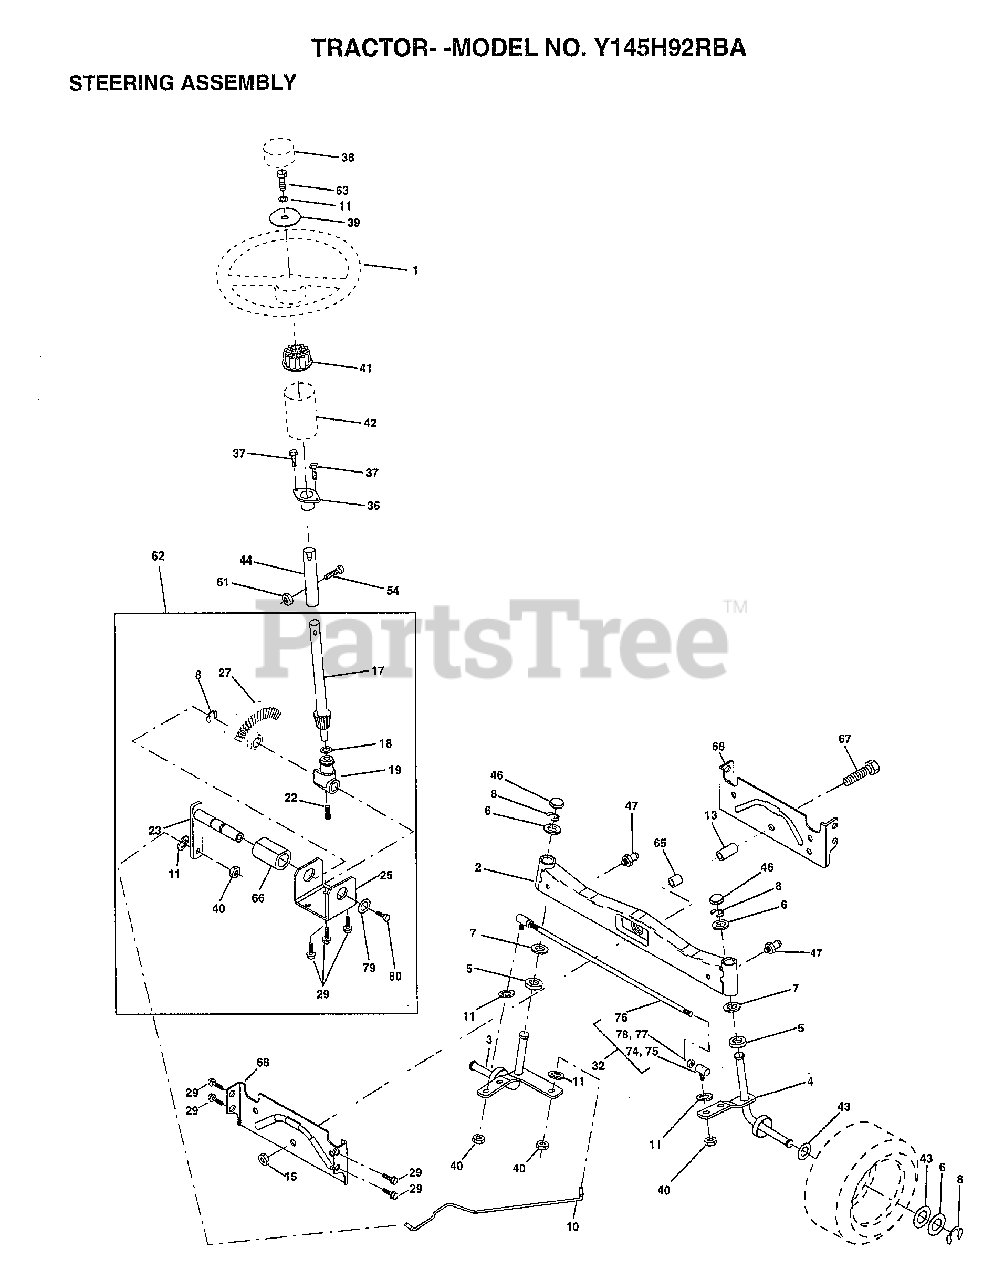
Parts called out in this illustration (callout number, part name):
3	"SPINDLE ASM,LH"
4	"SPINDLE ASM,RH"
5	WASHER .T
6	WASHER
7	WASHER
8	RING
10	LINK.DRAG
11	LOCKWASHER
13	BEARING.FRT.SPACER.AXLE
15	"NUT-LOC,FLANGE LT"
17	SHAFT ASM STEERIN
18	THRUST WASHER
19	SUPPORT.SHAFT.STEER
22	SCREW.HX.WSH.HD
23	SHAFT.ASM.PITMAN
25	BRKT-STEERING
27	GEAR SECTOR
29	SCREW
32	ROD.ASM.TIE.BALL
36	BUSHING.STEERING
37	"SCREW-TT,10-32 FL"
38	ST WHL INSERT CAP
39	WASHER T
40	GRIPCO NUT
41	ADAPTER LT
42	BOOT.STEER.PL
43	WASHER
44	EXT SHAFT STEERIN
46	CAP
47	ZERK M
51	NUT
54	BOLT
62	KIT.STEER.ASM
63	BOLT
65	SPACER AXLE
66	"BEARING-ARM,PITMA"
67	BOLT
68	BRACE AXLE
74	WASHER
75	JOINT.LH
77	NUT
78	NUT
79	WASHER
80	BOLT.HX.NYLON3/8-16X3/
